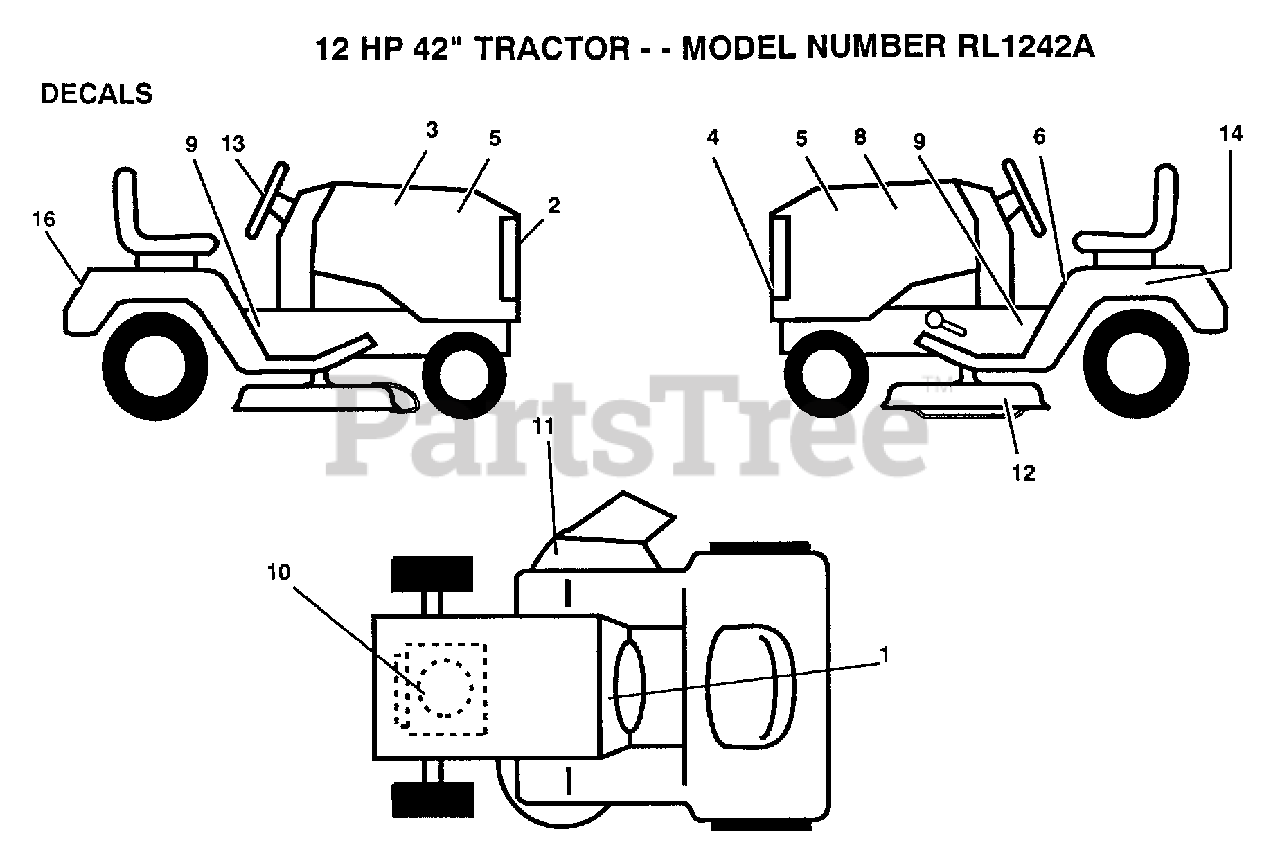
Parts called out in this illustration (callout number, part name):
2	GRILL DECAL
5	"DECAL,HOOD"
6	DECAL CAUTION
9	CHASSIS DECAL
10	DECAL.ENG.271967
11	DECAL WARNING
12	DECAL YT
13	"DECAL,STR WHL"
14	DECAL
16	FENDER DECAL
